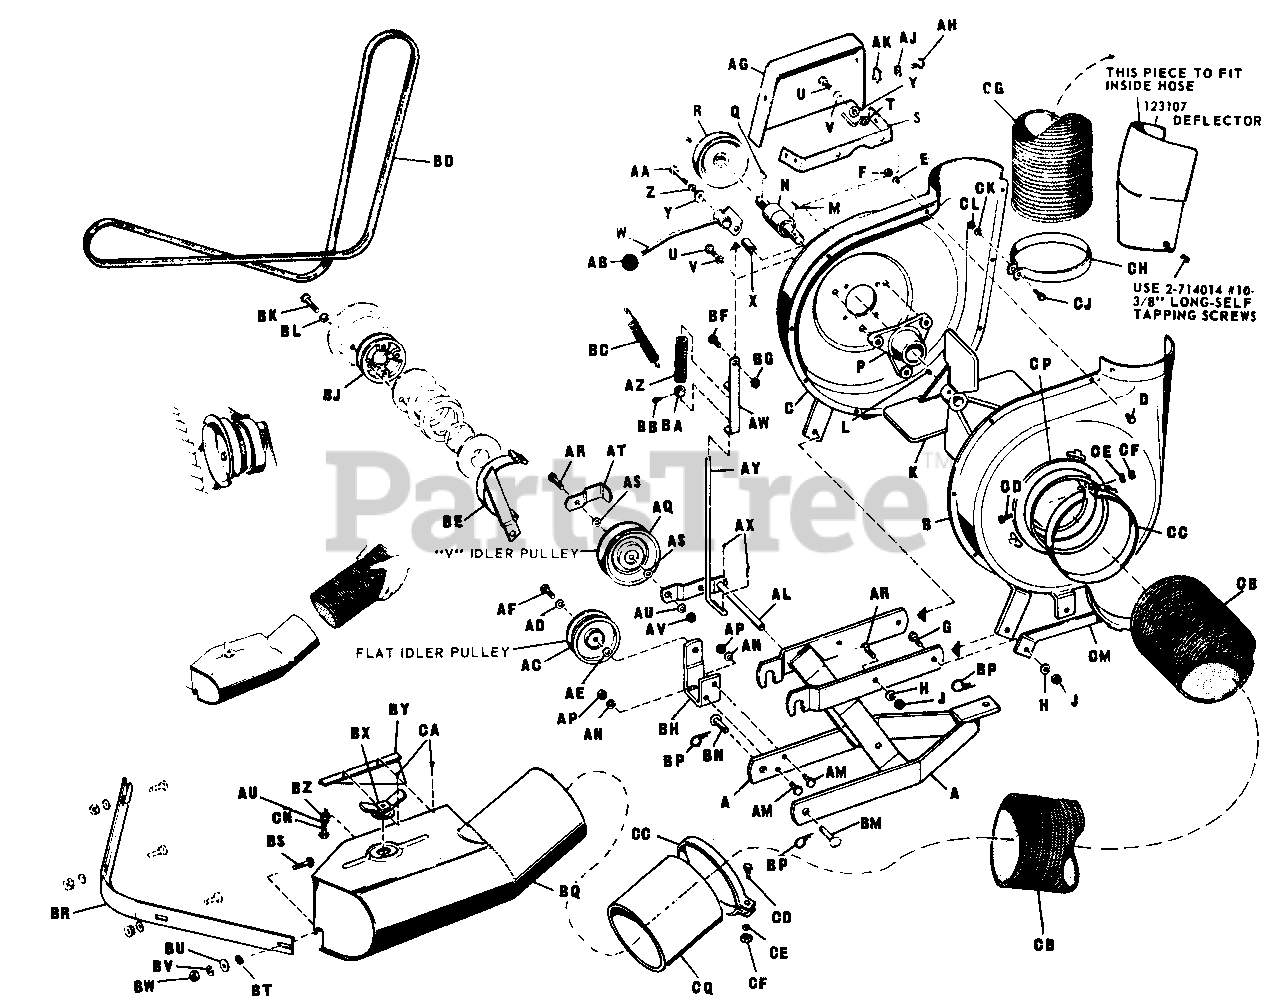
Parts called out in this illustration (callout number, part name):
A	Blower Housing Support Assembly
B	Housing Assembly, Inlet Half
C	Blower Housing Half Assy., R.H.
D	Hex Capscrew, 1/4"-20 x 1/2 " lg.
E	Lock Washer, 1/4"
F	Hex Nut, Full, 1/4"-20
G	Hex Capscrew, 3/8"-16 x 1" lg.
H	Lock Washer, 3/8"
J	Hex Nut, Full, 3/8"-16
K	Fan Assembly
L	Set Screw, Cup Pt., 5/16"-18 x 1/2"
M	Hi-Pro Key, 3/16" x 3/4" Dia.
N	Shaft & Bearing*
P	Flange, Shaft & Bearing*
Q	Hi-Pro Key, 3/16" x 3/4 Dia.
S	Belt Guard Bracket
T	Belt Stop
U	Hex Capscrew, 3/8"-16 x 1-1/4" lg.
V	Lock Washer, 3/8"
W	Clutch Lever Assembly
X	Clutch Lever Spacer
Y	Plain Washer, 5/16"
Z	Lock Washer, 3/8"
AA	Hex Capscrew, 3/8"-16 x 2" lg.
AC	Idler Pulley
AD	Lock Washer, 3/8"
AE	Plain Washer, 5/16"
AF	Hex Capscrew, 3/8"-16 x 1" lg.
AG	Belt Guard
AH	Hex Capscrew, 5/16"-18 x 5/8" lg.
AJ	Lockwasher, 5/16"
AK	Nut, Retainer
AL	Idler Arm Assembly
AM	Hex Capscrew, 5/16"-18 x 1" lg.
AN	Lock Washer, 5/16"
AP	Hex Nut, 5/16"-18
AQ	Idler Pulley
AR	Hex Capscrew, 3/8"-16 x 1-1/2" lg.
AS	Plain Washer, 3/8"
AT	Belt Stop
AU	Lock Washer, 3/8"
AV	Hex Nut, Full, 3/8"-16
AW	Rod Guide Assembly
AX	Cotter Pin, 3/32" x 3/4" lg.
AY	Clutch Rod
BB	Set Screw, Cup Pt., 1/4"-20 x 3/8
BE	Belt Guard Assembly
BF	Hex Capscrew, 5/16"-18 x 5/8" lg.
BG	Lock Nut, 5/16"-18
BH	Idler Support Bracket
BK	Hex Capscrew, 5/16"-18 x 1-3/4" lg
BL	Lock Washer, 5/16"
BM	Pin
BP	Spring Clip
BQ	Housing Assembly, Side Collector
BR	Front Baffle
BS	Carriage Bolt, 3/8"-16 x 1-1/4" lg.
BV	Lock Washer, 3/8"
BW	Hex Nut, Full, 3/8"-16
BX	Nut Assembly
BY	Baffle (To be used with new 42" Mower)
BZ	Hex Nut 3/8 x 16NC
CA	Self-Tapping Screw, #10-24 x 1/2" lg.
CB	Intake Hose, 7" Dia.
CC	Hose Clamp
CD	Hex Capscrew, 1/4"-20 x 3" lg.
CE	Lock Washer, 1/4"
CF	Hex Nut, Full, 1/4"-20
CG	Exhaust Hose, 6" Dia.
CH	Hose Clamp
CJ	Hex Capscrew, 1/4"-20 x 3 lg.
CK	Lock Washer, 1/4"
CL	Hex Nut, Full, 1/4"-20
CM	Hose support Assembly
CN	Carriage Bolt, 3/8"-16 x 1" lg.
CQ	Hose Extension
